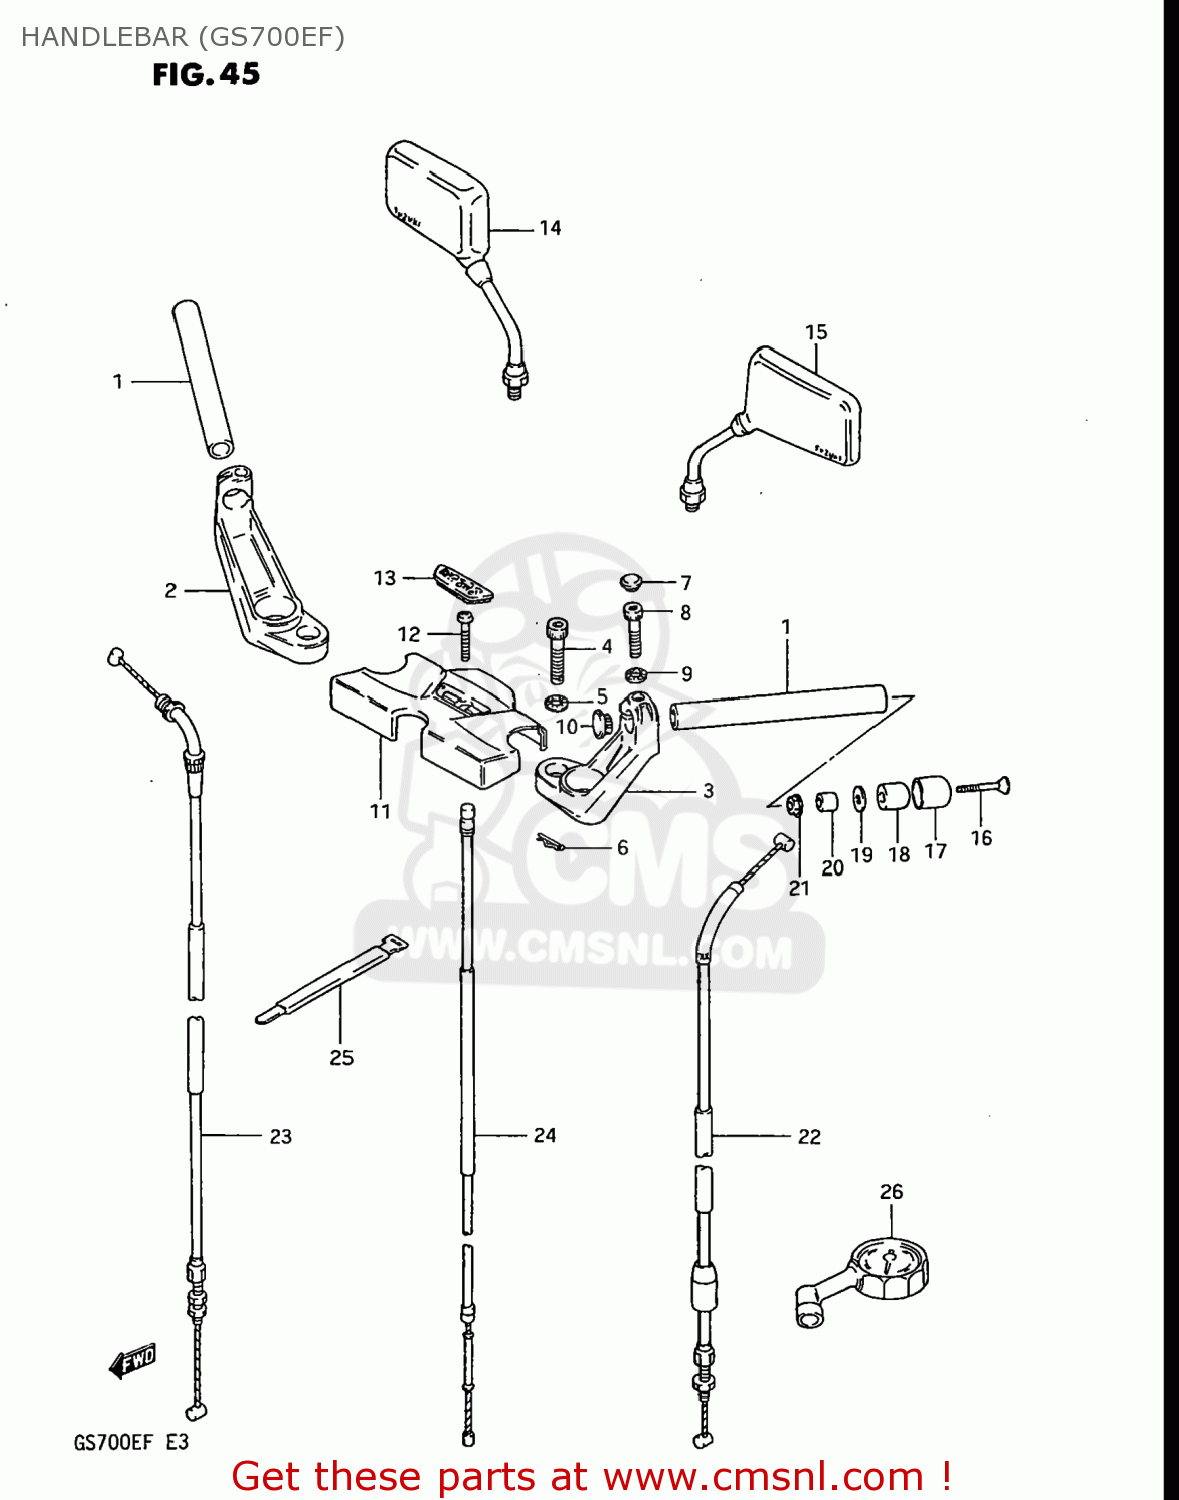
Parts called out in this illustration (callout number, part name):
1	HANDLEBAR
2	HOLDER,HANDLEBAR,RIGHT
3	HOLDER,HANDLEBAR,LEFT
4	BOLT 10X50
5	WASHER
6	CLIP
7	CAP(OD:14.5)
8	BOLT 8X35
9	WASHER
10	CAP,GRIP END
11	PAD,HANDLE
12	SCREW
13	CAP,HANDLE PAD
14	MIRROR ASSEMBLY,RIGHT
15	MIRROR ASSEMBLY,REAR VIEW
16	SCREW 6X65
17	CAP,BALANCER
18	BALANCER,HANDLE
19	SPACER,BALANCER
20	EXPANDER,BALANCER
21	NUT
22	CABLE ASSY,CLUTCH
23	CABLE ASSEMBLY,THROTTLE
24	CABLE COMP,STARTER
25	CLAMP
26	GAUGE ASSY,AIR PRESSURE
